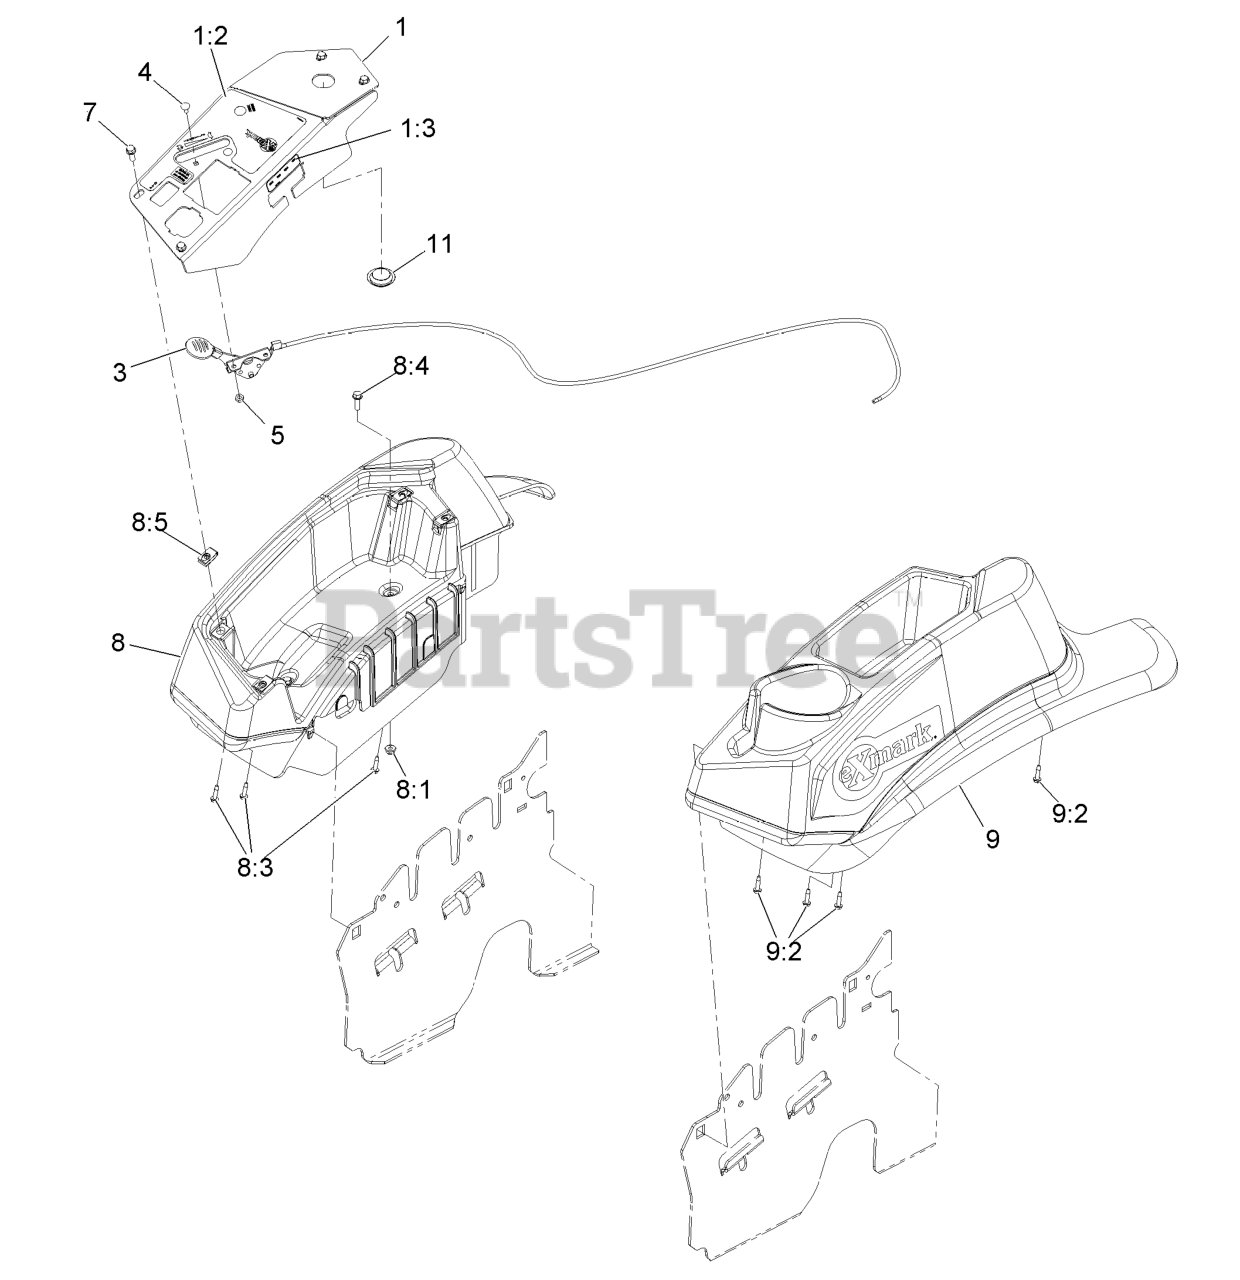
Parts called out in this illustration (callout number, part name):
1	ASM,CONTROL PANEL W/DECAL
1:2	DECAL,CONTROL PANEL EFI
1:3	DECAL-FUSE
3	ASM,THROTTLE CABLE
4	BOLT-CARR
5	NUT-LOCK, NI
7	SCREW-HWH
8	CONSOLE,RH NARROW ASM
8:3	SCREW,THD FORM,HWH
8:4	SCREW-HWH
8:5	Nut-Retainer-Panel 1/4-20
9	CONSOLE.LH NARROW ASM
9:2	SCREW,THD FORM,HWH
11	PLUG-PLASTIC
